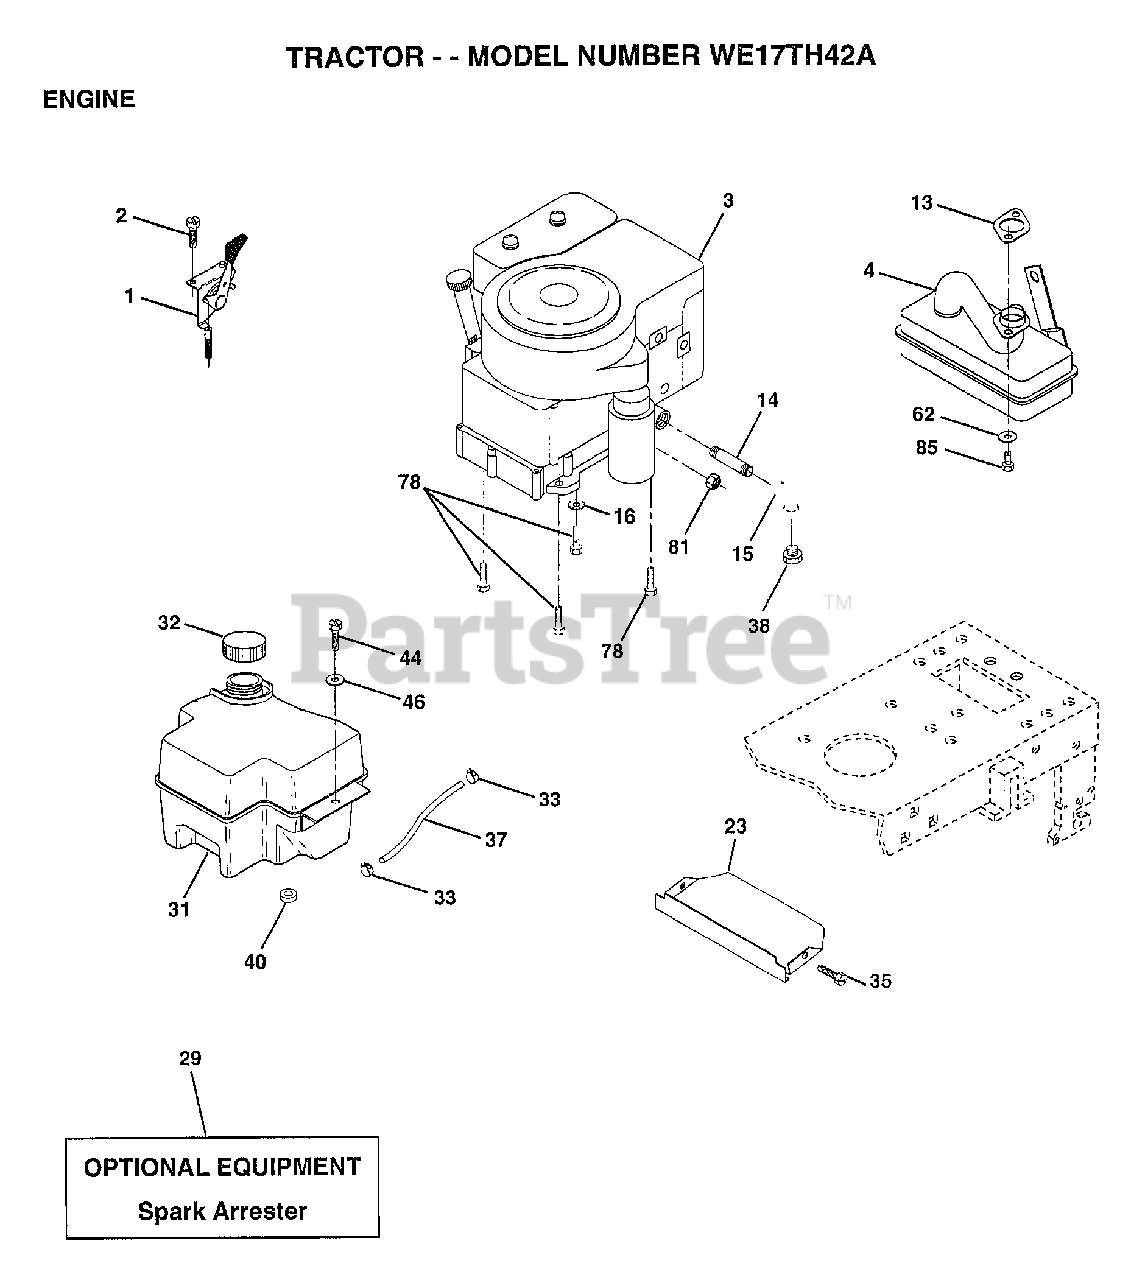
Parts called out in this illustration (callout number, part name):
1	CONTROL THROTTLE
2	SCREW LT
4	MUFFLER
13	GASKET MUFFLE TEC
14	PIPE NIPPLE
15	ELBOW
16	LOCKWASHER
23	SHIELD.BRN/DBR.GD
31	TANK.FUEL.FRONT.
32	CAP ASM FUEL
33	HOSE CLAMP
35	SCREW
37	LINE FUEL
44	SCREW HEX CRT
46	WASHER
62	LOCKWASHER
78	SCREW
81	NUT
85	SCREW HEX HD CAP
